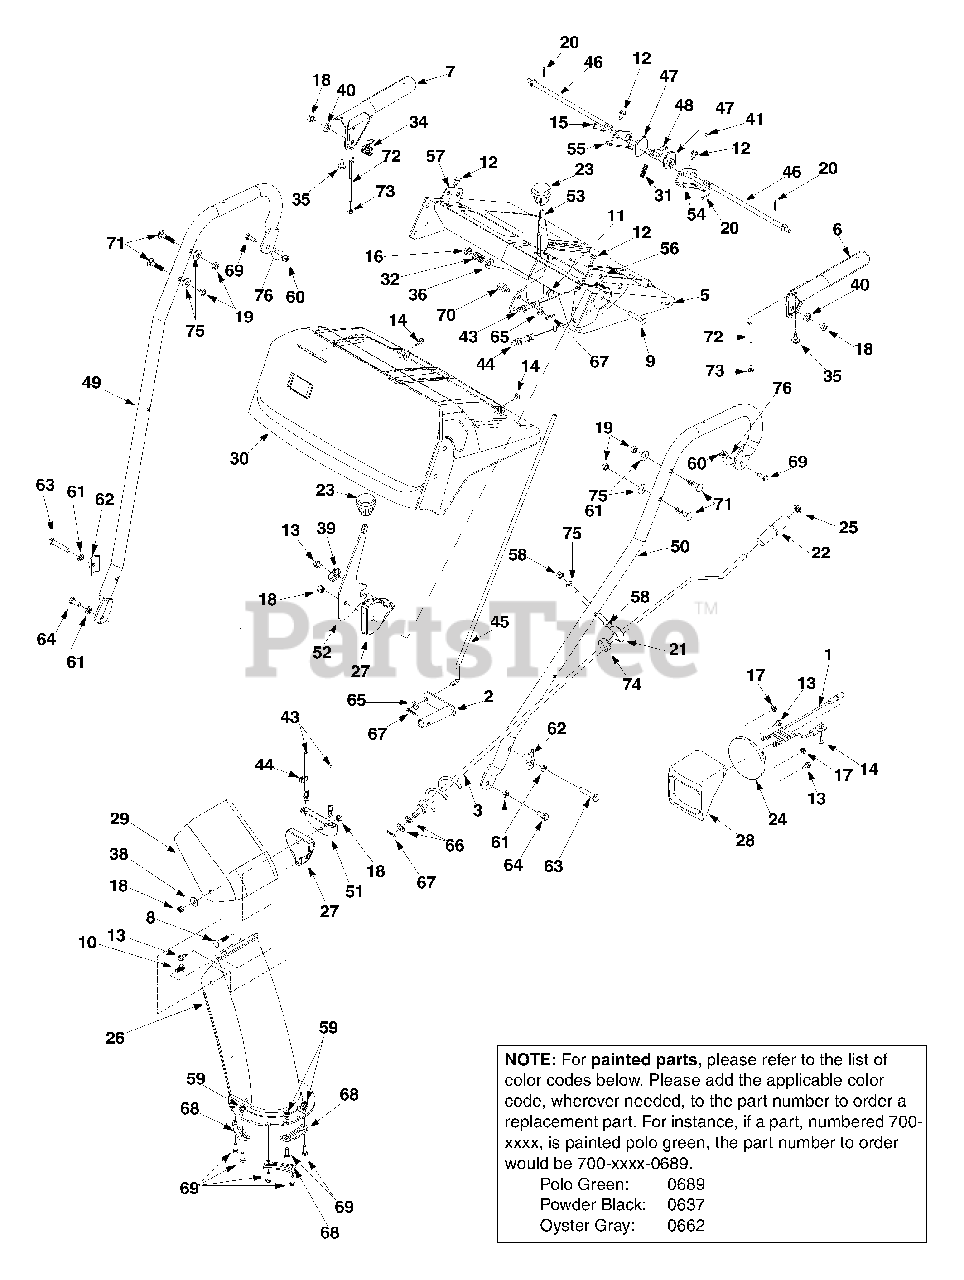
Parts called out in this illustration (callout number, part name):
1	Harness for Headlight
3	Chute Directional Control
6	Handle Assembly Engagement LH
7	Handle Assembly Engagement RH
8	Carriage Bolt 5/16-18 x 1.50
9	Hex Bolt 5/16-18 x 1.5
10	Carriage Bolt 5/16-18 x.75
11	Hex Screw 3/8-24 x 1.5
12	TT Screw 1/4-20 x 0.5"
13	Hex AB Tap Screw 1/4 x .62
14	Hex B-Tapp Screw # 10-16 x .62
15	Clevis Pin
16	Hex Ins. Lock Nut 3/8-24
17	Self-Threading Nut
18	Lock Nut 5/16-18
19	Lock Nut 5/16-18
20	Cotter Pin
21	Eye Bolt
22	Chute Directional Control Knob
23	Shift Knob
24	Headlight
25	Push Cap
26	Lower Chute
27	Cable Guide
28	Headlight Bezel
29	Upper Chute
30	Handle Panel
31	Compression Spring
32	Compression Spring
34	Torsion Spring
35	Rubber Bumper
36	Bell Washer .380 x .880 x .062
38	Special Washer
39	Special Washer
40	Grease
43	Chute Deflector Control Cable
44	Chute Deflector Cable w/ Clip
45	Shift Rod
46	Cam Rod
47	Cam Handle Lock
48	Pawl Handle lock
58	Hex Nut 5/16-18 Thd.
59	Hex Flange Locked Nut 1/4-20 Thd.
60	Hex Nut 1/4-20
61	Lock Washer 5/16
62	Handle Tab
63	Hex Bolt 5/16-18 x 1.75 Gr.5
64	Hex Bolt 5/16-18 x 0.75" Gr. 5
65	Flat Washer 5/16
66	Flat Washer 3/8 x .738 x .063"
67	Hairpin Clip
68	Chute Flange Keeper
69	Hex Bolt 1/4-20 x 0.75" Gr.5
70	Ferrule
71	Carriage Bolt 5/16-18 x 1.50
72	Z Fitting
73	Hex Nut # 10-24
74	Rubber Grommet
75	Cupped Washer
76	Bell Washer
